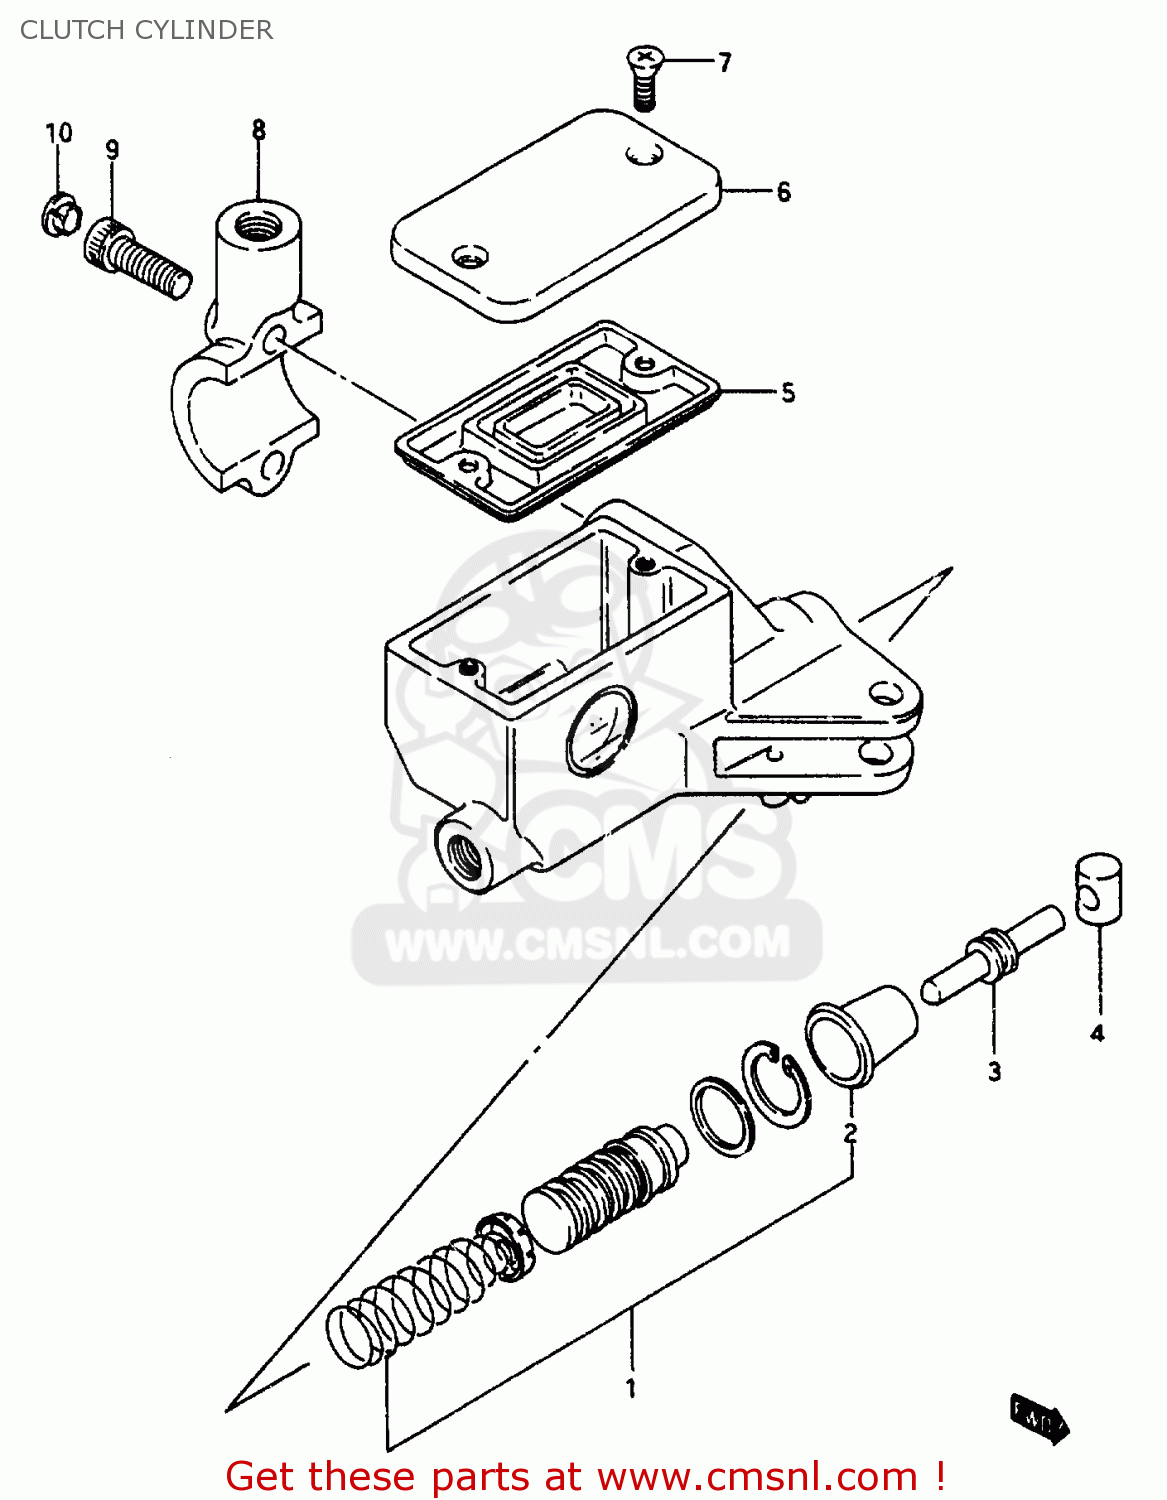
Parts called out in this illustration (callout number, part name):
1	PISTON & CUP SET
2	BOOT
3	PUSH ROD
4	BUSH
5	6
6	CAP
7	SCREW
8	HOLDER
9	BOLT
10	CAP(OD:10)
